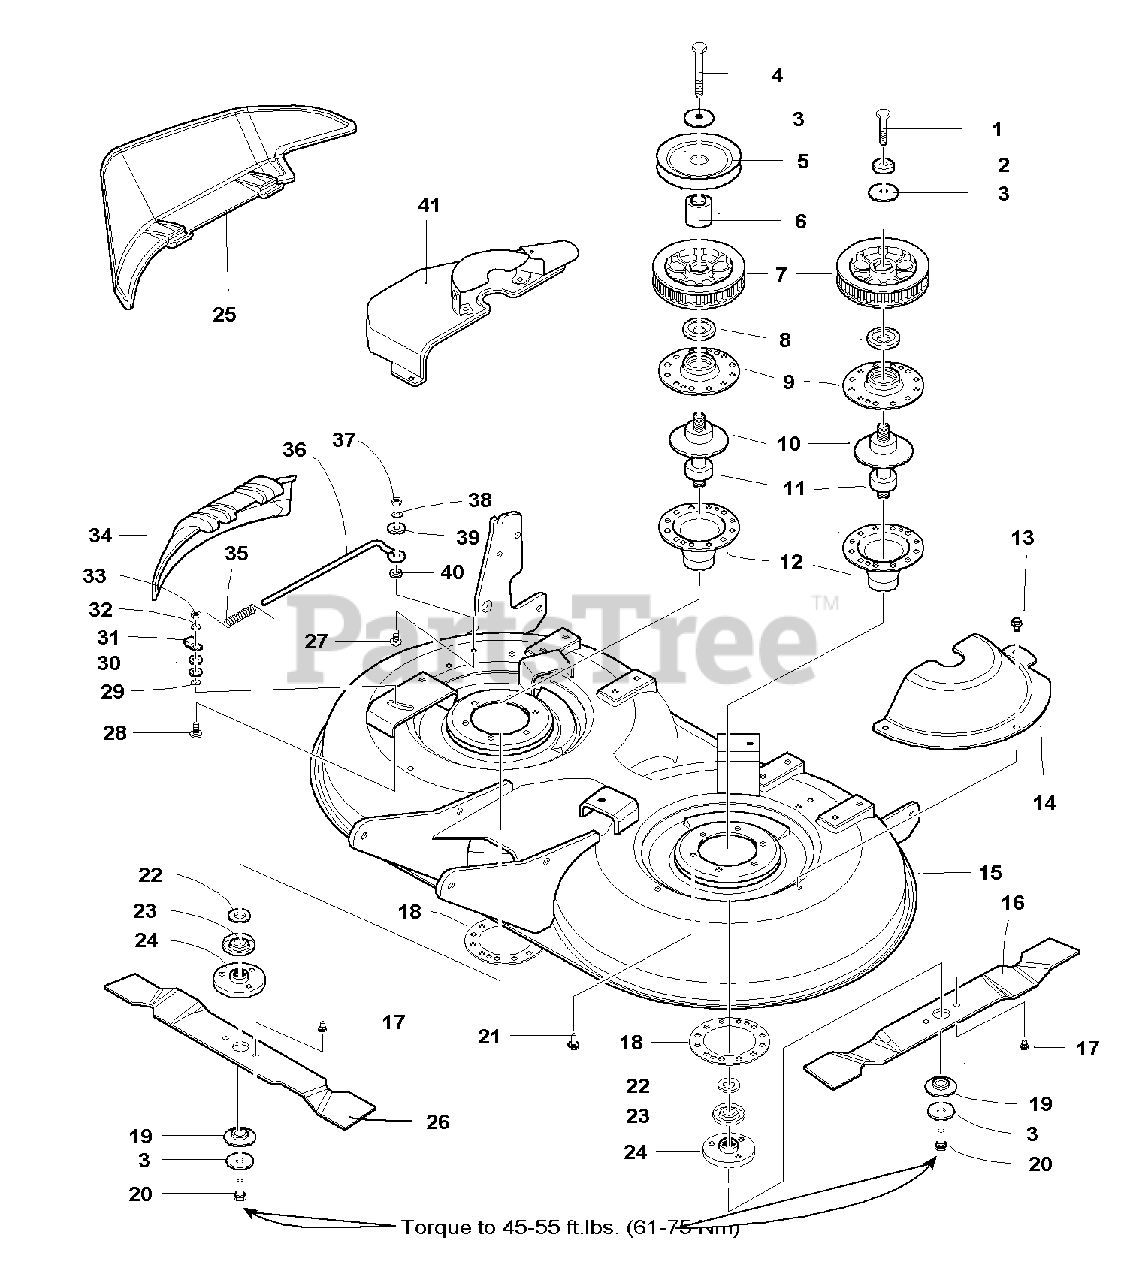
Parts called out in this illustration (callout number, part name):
1	CAPSCREW, Hex Head, 7/16-14 x 2-3/4 G8
2	WASHER, 7/16
3	WASHER, Spring
4	CAPSCREW, Hex Head, 7/16-14 x 4-1/2 G8
7	SPROCKET & FLANGE ASSEMBLY, Riveted
8	SHIELD, Bearing Upper, Arbor
9	HOUSING, Arbor Top
10	GASKET, Foam Poly
11	ARBOR SHAFT & BEARINGS ASSEMBLY
12	HOUSING, Arbor Bottom with Lube Fitting
13	CAPSCREW, Taptite Hex Washer Head, 5/16-18 x 1/2
14	COVER, Arbor, LH
15	HOUSING ASSEMBLY, 40", Orange
15	HOUSING ASSEMBLY, 40", Red
15	HOUSING ASSEMBLY, 40", Black
16	BLADE, Mower, LH
18	ADAPTOR, Arbor
19	WASHER, Spline
20	CAPSCREW, Hex Head, 7/16-14 x 2-1/4 G8
21	CAPSCREW, Taptite Hex Washer Head, 5/16-18 x 3/4
22	WASHER, Shim
23	SHIELD, Arbor Bearing, Lower
24	ADAPTER, Blade
25	DEFLECTOR, Discharge
26	BLADE, Mower, RH
27	CARRIAGE BOLT, 5/16-18 x 1
28	CARRIAGE BOLT, 1/4-20 x 7/8
29	NUT, Push
30	WASHER, 1/4
32	LOCKWASHER, Spring 1/4
33	NUT, Hex 1/4-20
34	DOOR, Mulching, Black Plastic
35	SPRING, Torsion
37	NUT, Hex 5/16-18
38	LOCKWASHER, Spring 5/16
39	WASHER, 5/16
40	NUT, Push
41	COVER, Arbor, RH
